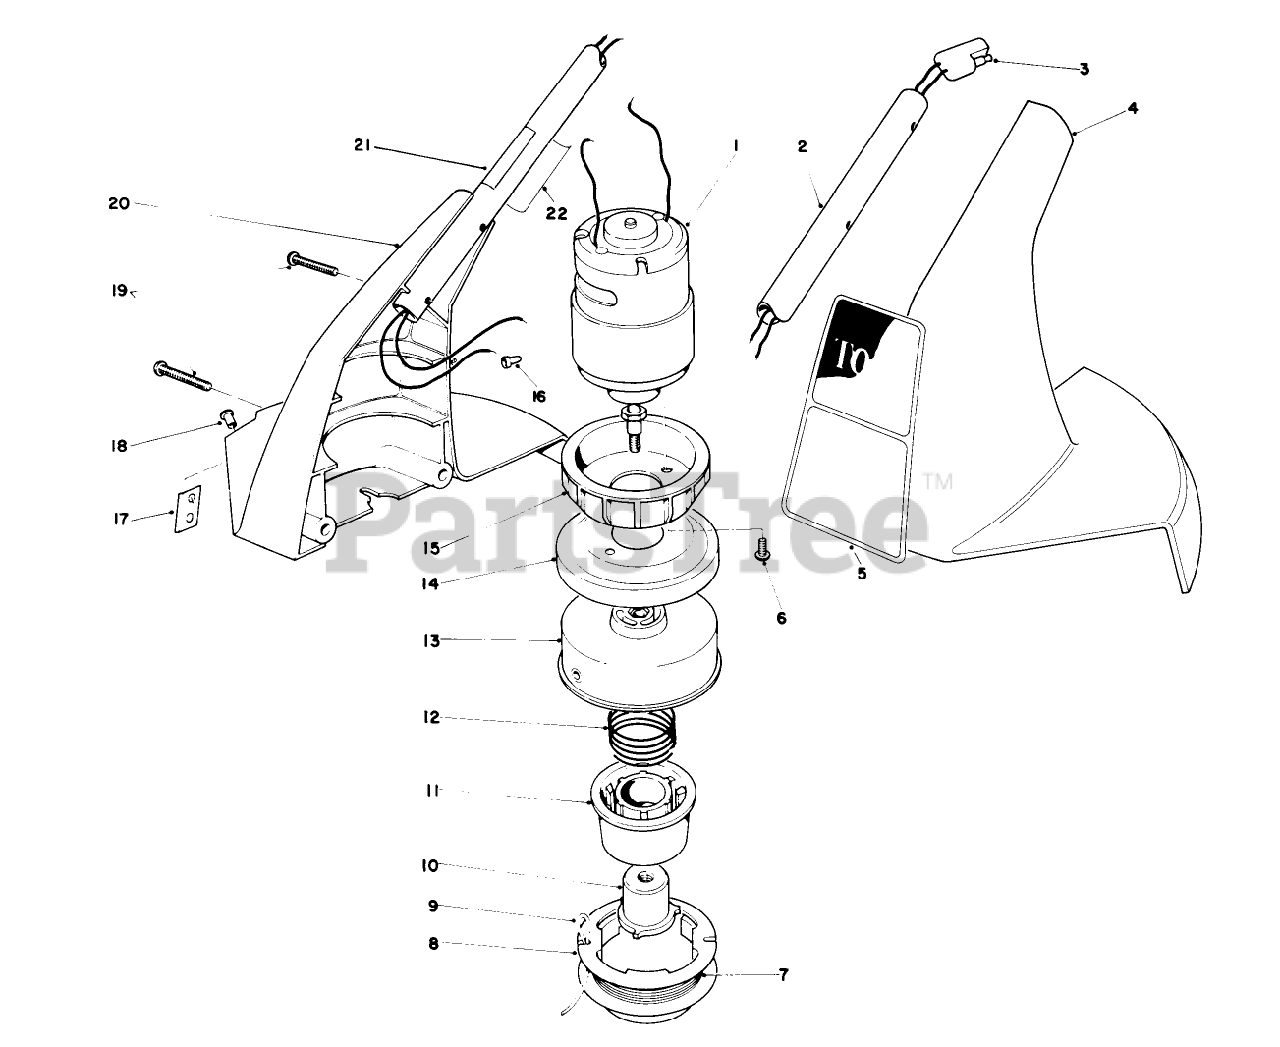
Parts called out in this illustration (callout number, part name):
7	Cutting Line (12- .05 Dia.)
8	CAP-SPOOL
9	Cutting Line (30- .05 Dia.)
10	DRIVER
11	CORE - SPOOL
16	CONNECTOR SCREW
17	Knife Blade
18	Rivet
19	SCREW-PLASTITE
